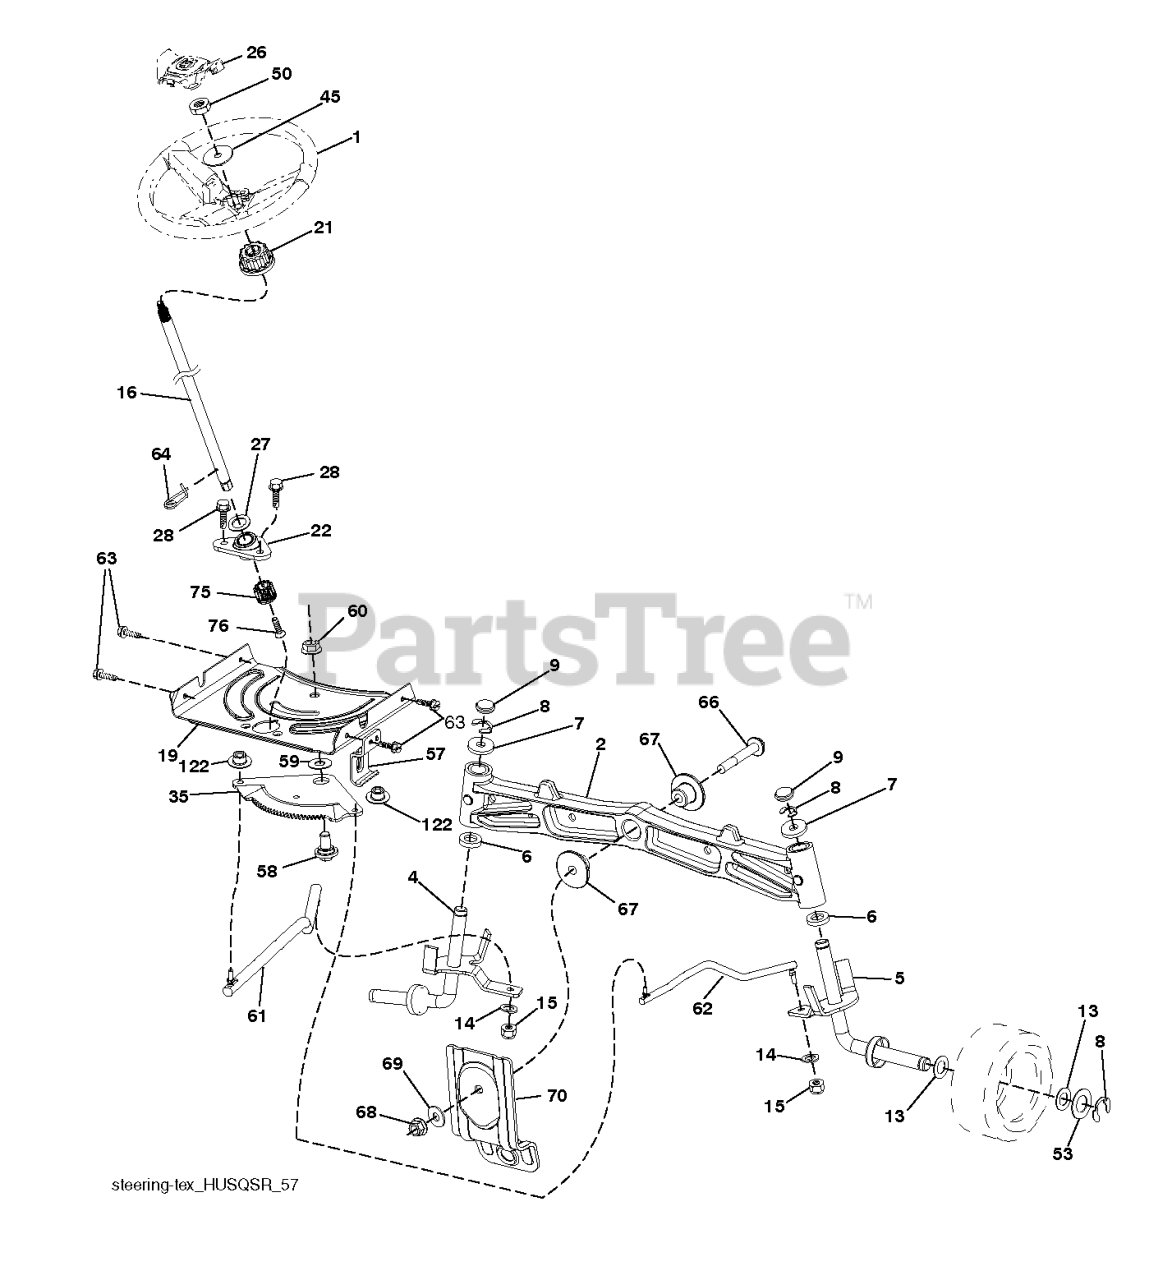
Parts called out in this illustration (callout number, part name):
1	WHEEL.STEER.HUSQ.SR.498.OVMLD
2	AXLE.CAST.IRON
4	SPINDLE.WELDED.LH.15"TEX
5	SPINDLE.WELDED.RH.15"T
6	THRUST WASHER
9	CAP.SPINDLE.BLACK
14	SLW 3/8 STD
15	NUT CROWNLOCK 3/8-24
16	SHAFT.STEER.2HIGH.SPLND.PLATED
19	PLATE.STEER.DDL.NLT/NG
21	ADAPTER.WHEEL.STEER.SPLND.ALUM
22	BEARING.SHAFT.STEER.LOWER.625
26	INSERT.CAP.WHL.STRG.HUSQ.PREM
28	SCREW, 3/8-16X3/4
35	GEAR.SECTOR.PLATE.DDL.
45	WASHER.3/8ID.2-3/8OD.12GA.PLTD
50	NUT LOCK FLG 3/8-16 UNC
53	WASHER.HARDENED
57	BRKT.UPSTOP.GT/LT.TEX
58	BOLT.SHOULDER.SECTOR.P
59	WASHER.THURST.SECTOR.S
60	NUT FLANGE LOCK 5/8-11
61	LINK.ASM.DRAG.ADJUST.LH.RAW
62	LINK.ASM.DRAG.ADJUST.RH.RAW
63	SCREW
64	RETAINER.CLIP.SPRING.S
66	BOLT HEX FGHD 7/16-14 X 3 SERR
67	BUSHING.PM.FRONT AXLE
68	NUT.LOCK.FLANGE.7/16
69	WASHER.1.5X.505X.118
70	BRACKET.FRT.DECK.SUSP.RR.MT431
75	PINION.ZINC PLATED
76	SCREW HEAD SOCKET LRVB
122	CAP.GEAR.SECTOR.TEX
